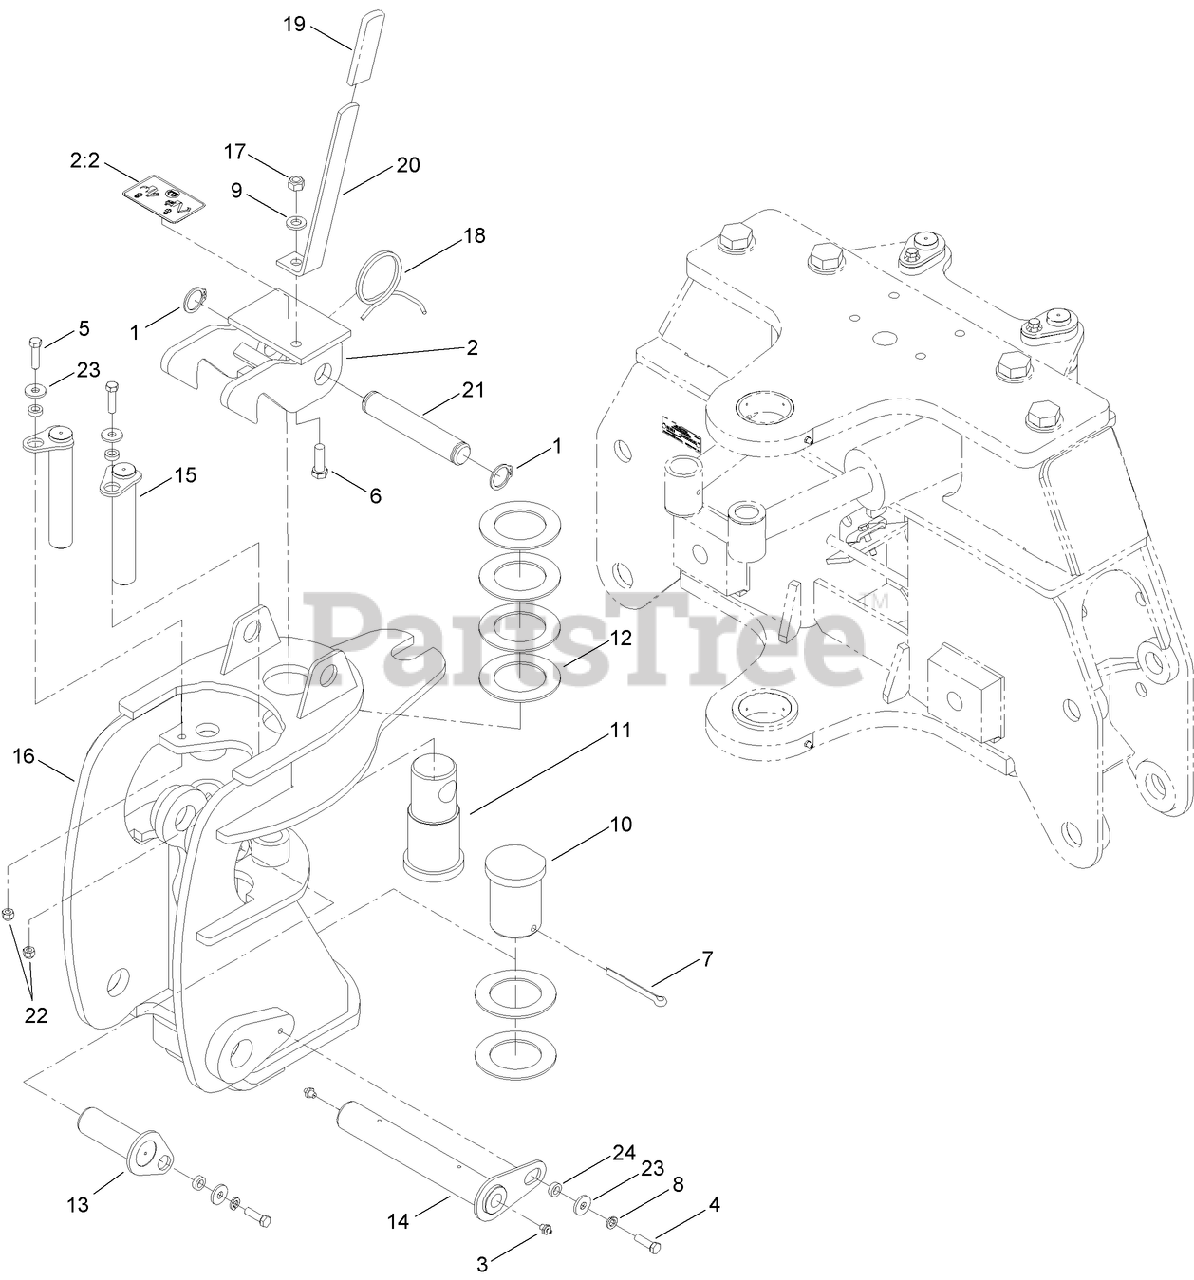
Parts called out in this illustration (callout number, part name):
1	RING-RETAINING, EXTERNAL
2	BOOM LOCK LATCH ASM
2:2	DECAL-OPERATOR PRESENCE
3	FITTING-GREASE
4	SCREW-HH
5	SCREW-HH
6	SCREW-HH
7	PIN-COTTER
8	WASHER-LOCK
9	WASHER-FLAT
10	PIN-PIVOT, LOWER
11	PIN-PIVOT, UPPER
12	WASHER-THRUST PIVOT
13	PIN-Boom Cylinder
14	PIN-BOOM PIVOT
15	PIN-PIVOT W/FLAG
16	FRAME-PIVOT
17	LOCKNUT
18	SPRING-Torsion
19	GRIP-HANDLE
21	PIN-PIVOT
22	NUT-HEX
